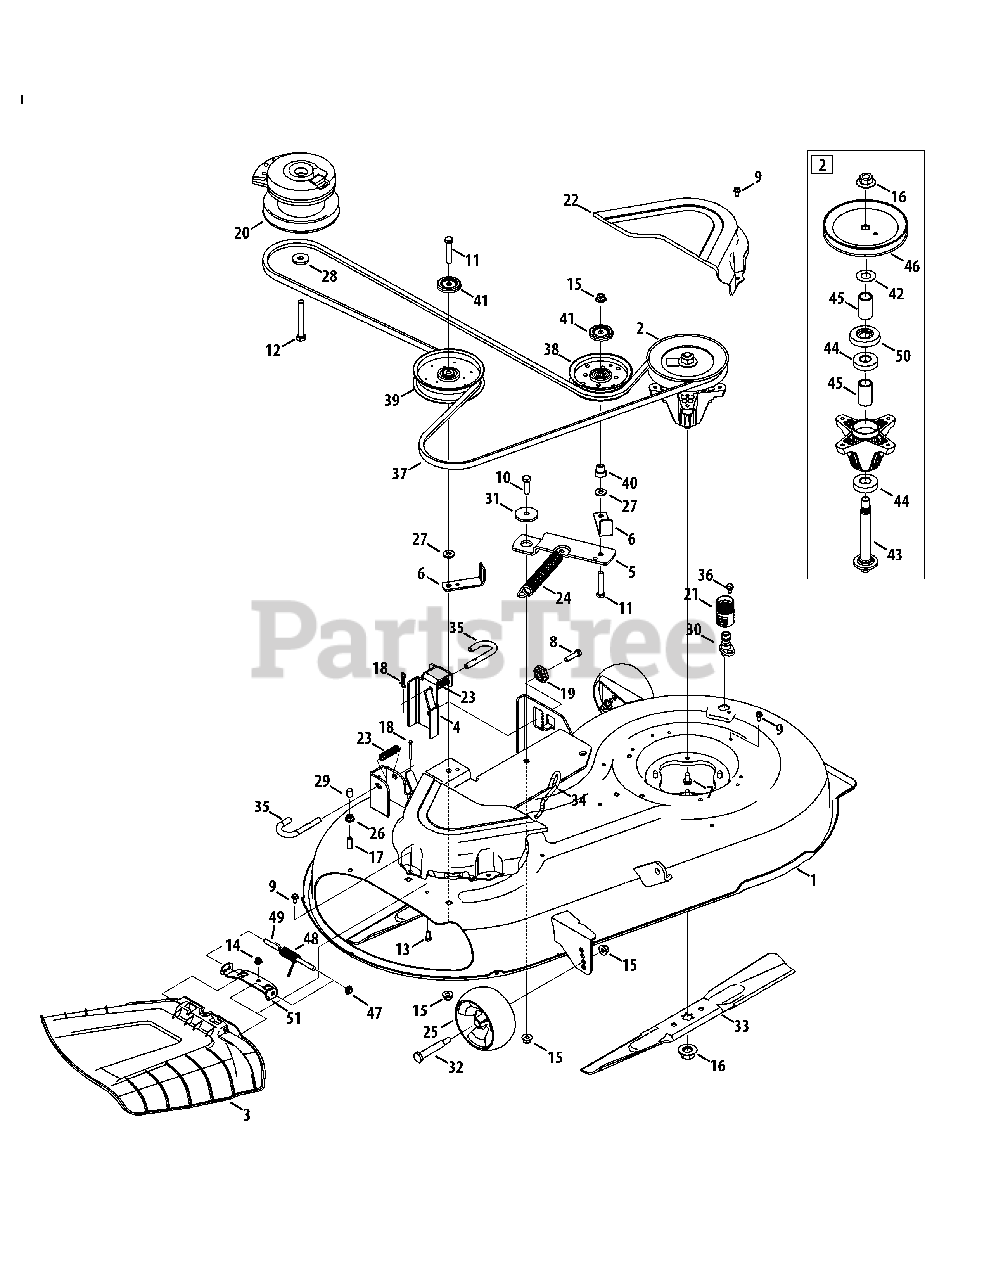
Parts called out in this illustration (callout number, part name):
1	42" Deck
2	Spindle Assembly
3	Chute Deflector Assembly
4	Deck Lift Bracket
5	Pivot Idler Bracket
6	Bracket Belt Guard
7	Hex Washer Screw, 5/16-18 x .750
8	Hex Cap Screw, 3/8-16 x 1.50
9	Hex Washer Screw, 1/4-20 x .625
10	Hex Cap Screw, 3/8-16 x 1.25
11	Hex Cap Screw, 3/8-16 x 2.00
12	Screw, 7/16-20 x 3.25
13	Hex Cap Screw, 1/4-20 x .62
14	Nut, Flange Lock, 1/4-20, Nylon
15	Flange Lock Nut, 3/8-16
16	Hex Flange Nut, 5/8-18
17	Hex Cap Screw, 5/16-18 x 1.00
18	Cotter Pin, 5/32 x 1.25
19	Deck Adjustment Gear
20	Electric PTO Clutch
21	Water Nozzle Adapter
22	Belt Cover
23	Compression Spring, .66 x 1.9
24	Extension Spring, .94 Dia. x 7.57
25	Deck Ball Wheel, 5.0
26	Flange Lock Nut, 5/16-18
27	Flat Washer, .385 x .870 x .092
28	Flat Washer, .450 x 1.25 x .164
29	Cap, .290 x .500
30	Deck Wash Nozzle
31	Shoulder Spacer, .884 x .190
32	Shoulder Screw, .5 x 2.5 x 3/8-16
33	Blade, 2 in 1, 21.23
34	Deck Spring Rod
35	Deck Hanger Rod
36	Shoulder Screw, 1/4-20 x 0.50
38	Idler Pulley, 4.25 Dia.
39	Idler Pulley, 5.00 Dia.
40	Shoulder Spacer
41	Pulley Cap
42	Washer, .760 x 1.50 x .030
43	Spindle Shaft
44	Ball Bearing
45	Spacer, .792 x 1.060 x 1.860
46	Deck Pulley
47	Push Cap
48	Spring, Torsion, .440 ID x 1.75
50	Bearing Shield
